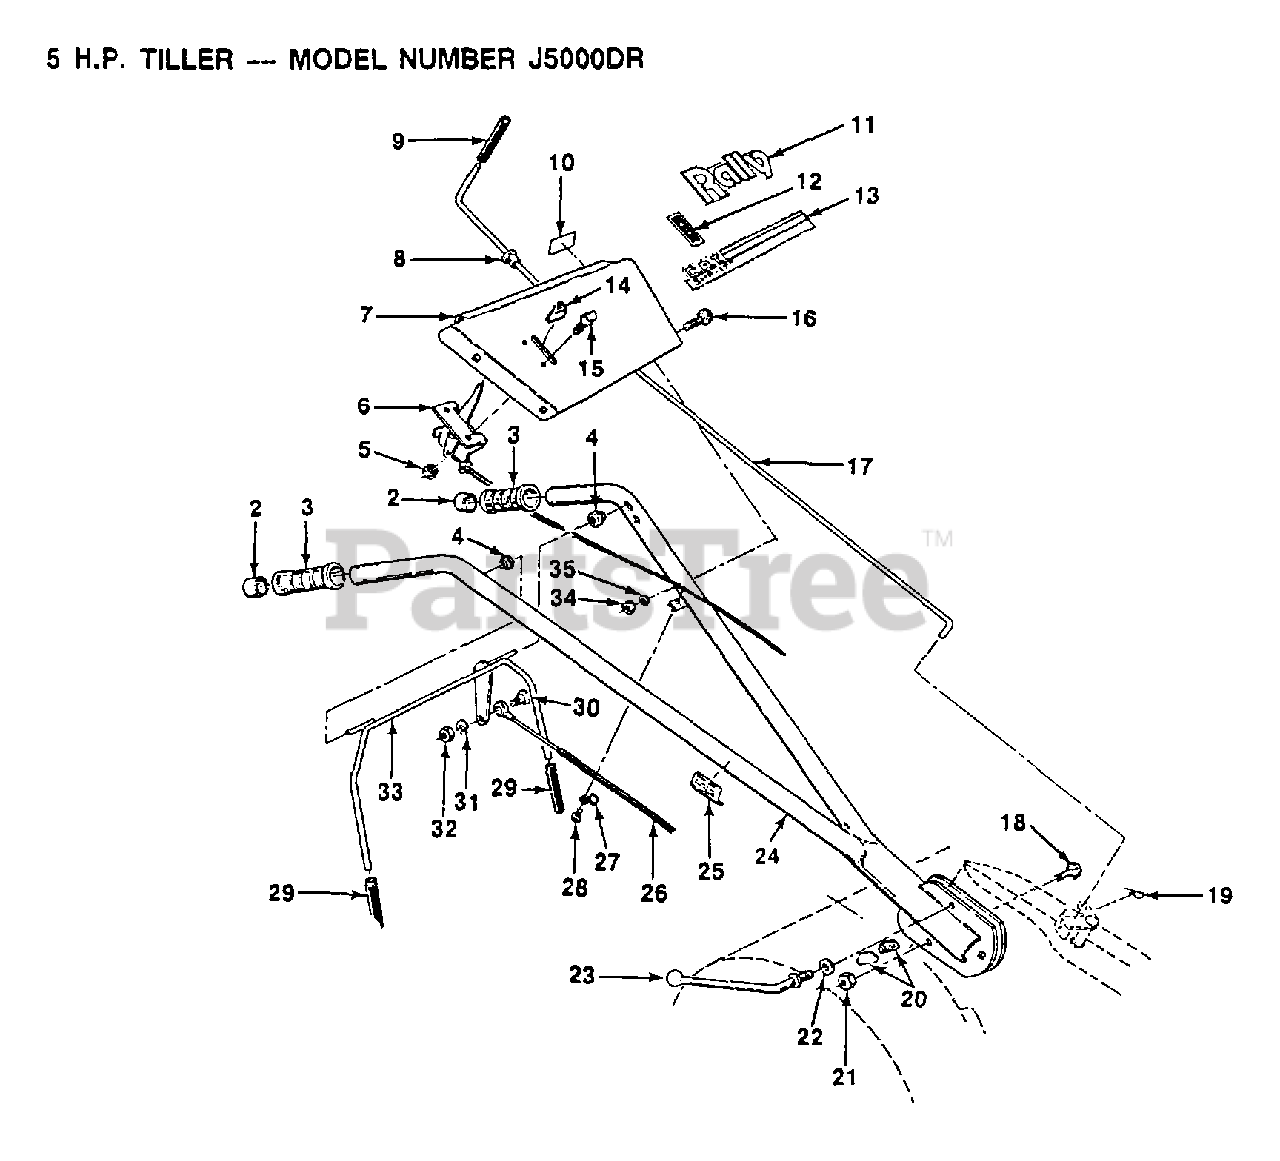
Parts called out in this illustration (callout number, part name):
2	CAP CRT
6	THROTTLE CRT
8	GROMMET TI
9	GRIP TI
12	DECAL, THROTTLE
13	DECAL, BRACKET HANDLE
14	KNOB CRT
15	SCREW
16	BOLT CARRIAGE CRT
17	ROD SHIFT CRT
18	BOLT D
19	RETAINER M
20	LOCK CRT
22	WASHER CRT
23	LEVER LOCK CRT
25	DECAL TI
26	CABLE.CLUTCH.CRT
27	CONDIUT CLIP T
29	GRIP BAR CRT
30	SHOULDER BOLT ST
31	LOCKWASHER
33	HANDLE BAR CRT
35	LOCKWASHER
